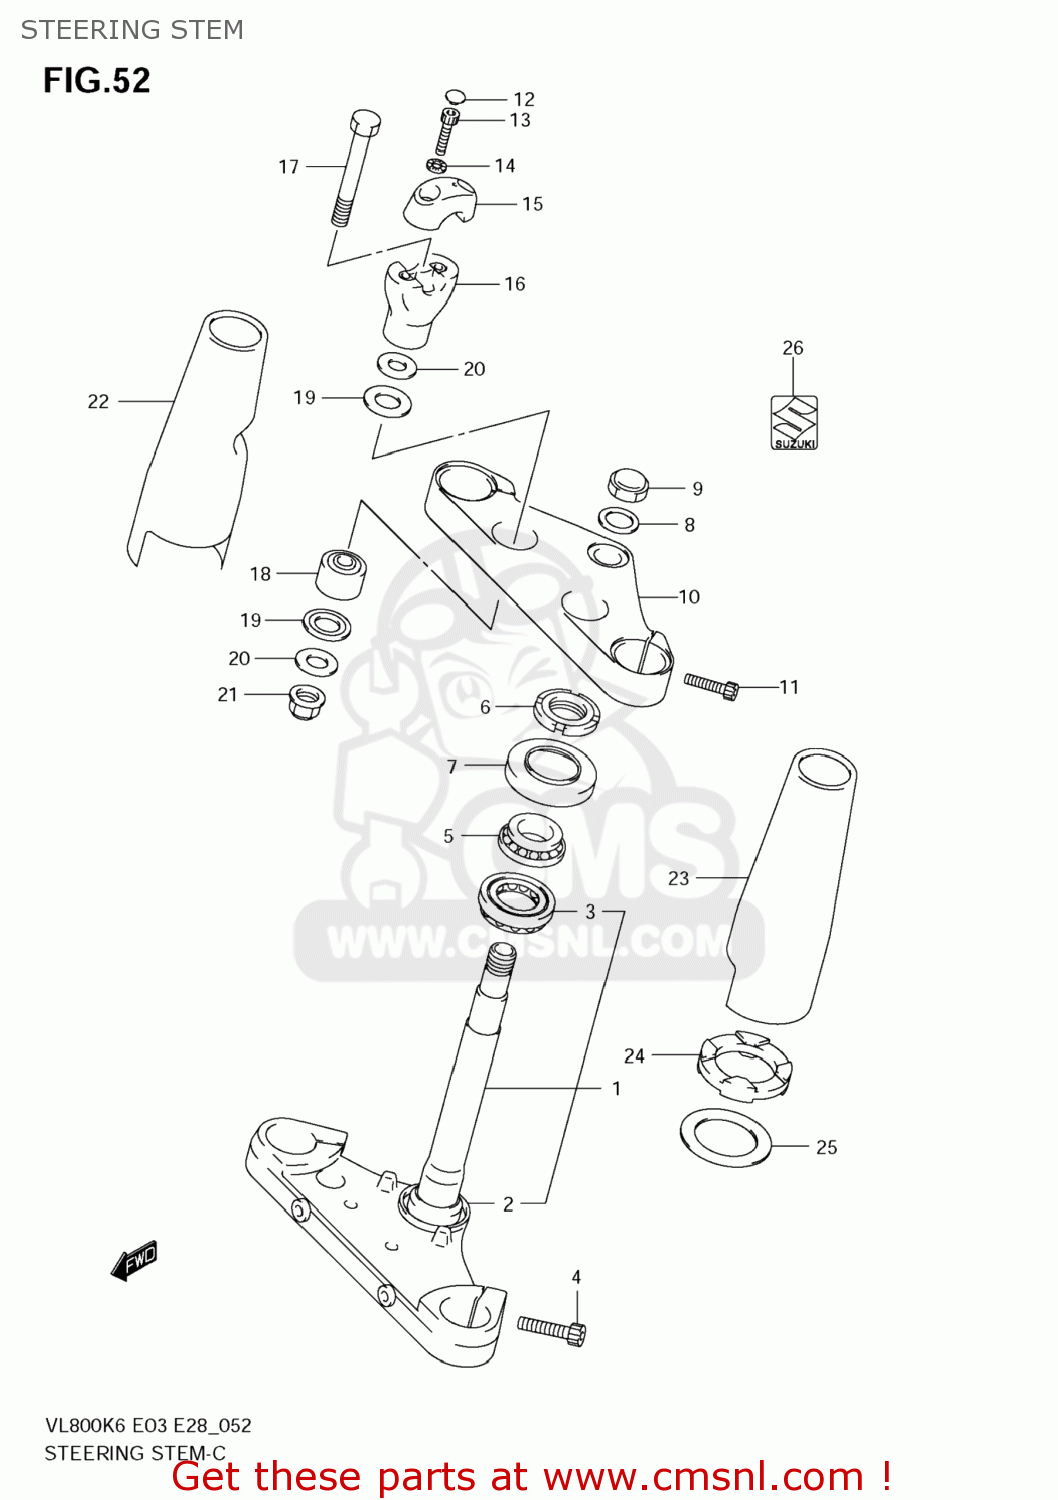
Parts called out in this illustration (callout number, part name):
1	STEM,STEERING
2	SEAL,STEERING LWR
3	BEARING(30X55X17)
4	BOLT
5	BEARING(25X47X15)
6	NUT,STEERING STEM(25X44X10)
7	DUST SEAL,STEERING UPR
8	WASHER(22.5X32X1.6)
9	NUT,CAP
10	HEAD,STEERING STEM
11	BOLT
12	CAP(OD:11)
13	BOLT,HANDLE HOLDER
14	WASHER
15	HOLDER,HANDLE UPR
16	HOLDER,HANDLE UNDER
17	BOLT
18	DAMPER,RUBBER
19	SEAT,RUBBER
20	WASHER
21	NUT
22	COVER,UPR,R
23	COVER,UPR,L
24	SEAT,RUBBER
25	WASHER
26	EMBLEM,S
